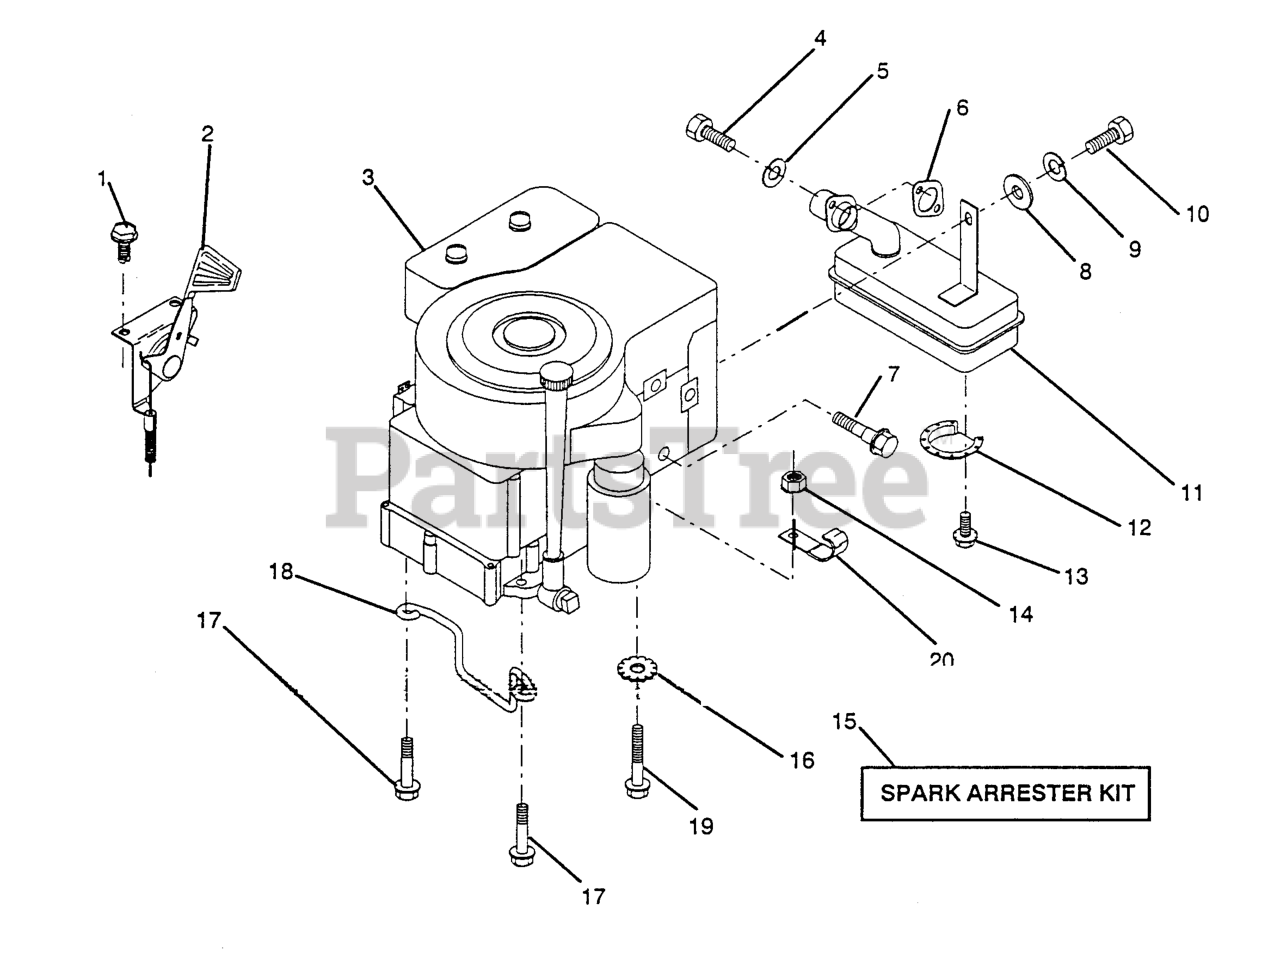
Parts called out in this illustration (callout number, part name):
1	SCREW
2	THROTTLE CONTROL
3	Engine, Briggs and Stratton Model No. 281707 Type No. 0122-01
4	SCREW
5	WASHER.LOCK.HVY.HLCL.SPR.5/16
6	GASKET ENGINE
8	WASHER
9	LOCKWASHER
10	BOLT
11	MUFFLER
12	DEFL MUFFLER LTV
13	SCREW
15	SPARK ARREST
16	LOCKWASHER
17	SCREW LT
18	KEEPER,DR BELT GR
19	Screw, Hex Wsh Hd Thdrol 3/8 - 16 x 2
20	CLIP T
